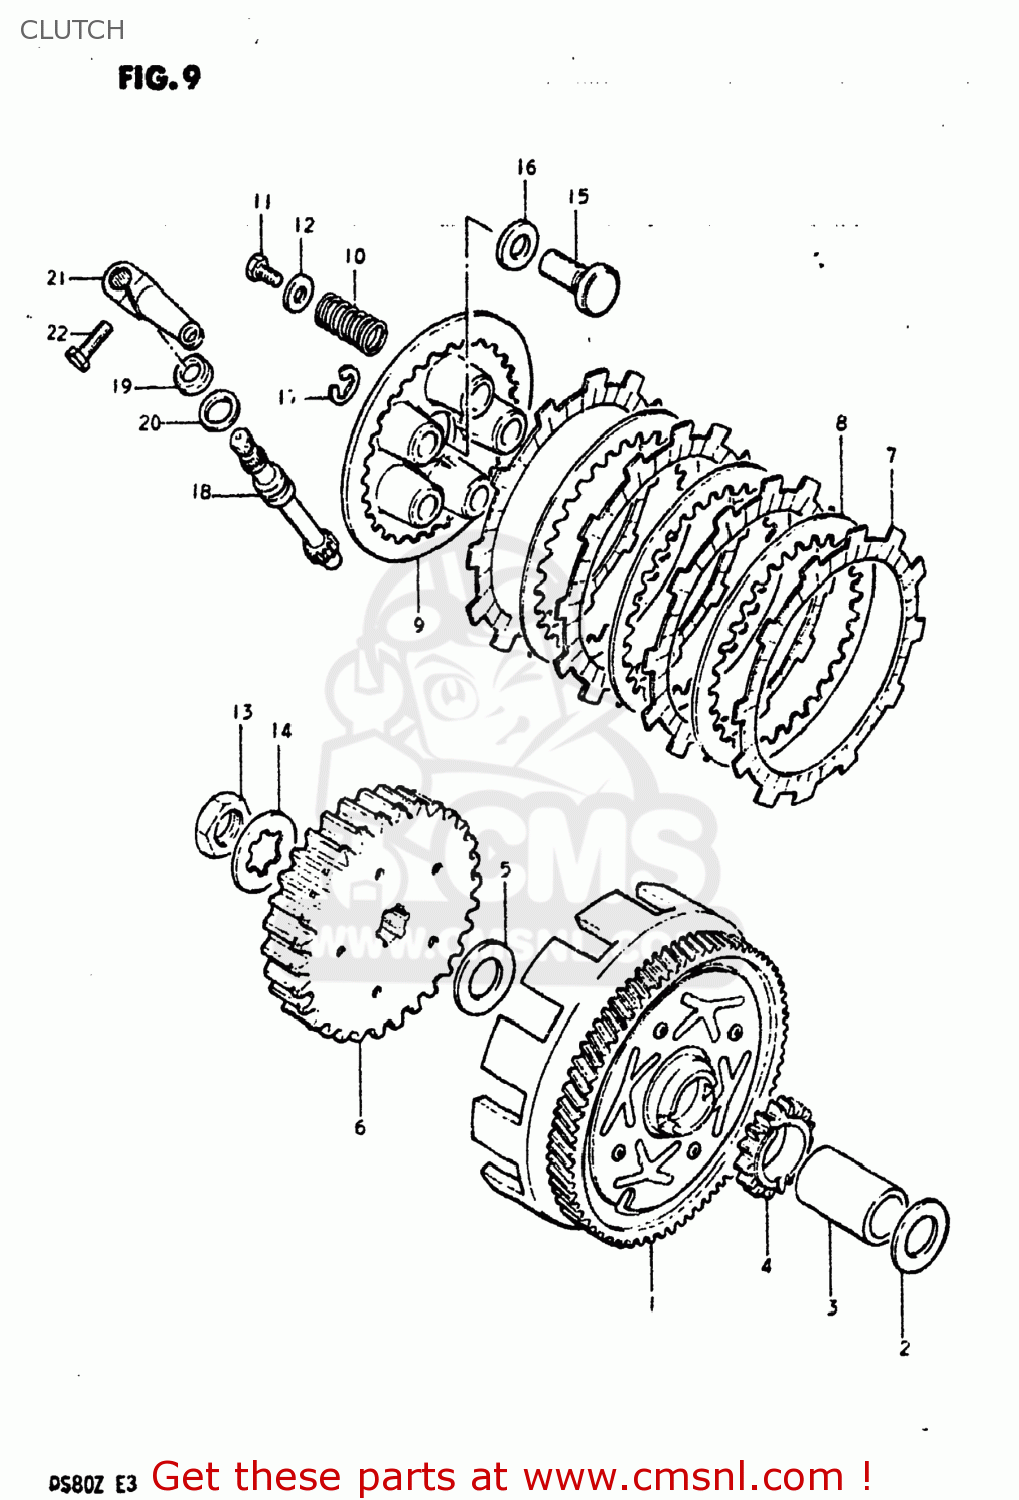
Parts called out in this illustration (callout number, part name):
1	GEAR ASSY,PRI DRIVEN(NT:73)
2	WASHER,THRUST
3	SPACER
4	GEAR,KICK STARTER DRIVE
5	WASHER
6	HUB,CLUTCH SLEEVE
7	PLATE,CLUTCH DRIVE
8	PLATE,CLUTCH DRIVEN (NAS)
9	DISC,CLUTCH PRESSURE
10	SPRING
11	BOLT(5X16)
12	WASHER (5.5X16X1.2)
13	NUT
14	WASHER,LOCK
15	RACK,CLUTCH RELEASE
16	BEARING(10X22X2.8)
17	E RING 8MM
18	PINION,CLUTCH RELEASE
19	OIL SEAL
20	WASHER (12X17X1)
21	ARM,CLUTCH RELEASE
22	BOLT, UPPER
